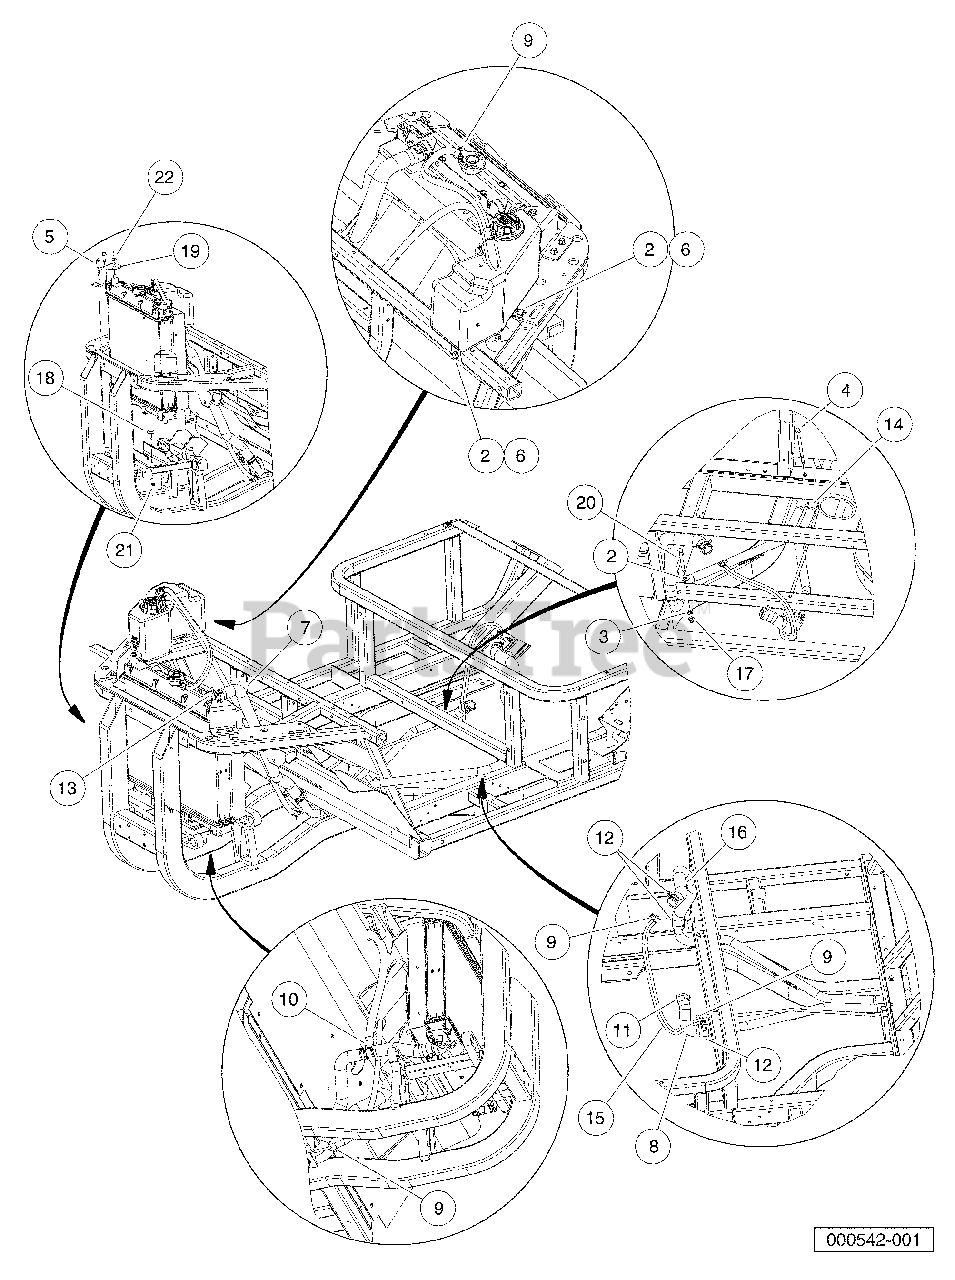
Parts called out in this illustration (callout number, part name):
1	Instl, Cooling Sys, Diesel
2	Washer, 5/16 Type B Flat
3	Spacer, 0.720"
4	Bolt-hex Fl, M8 X 1.25 X 135
5	Screw, M8X1.25X30, Hex
6	M8-1.25x20 Taptite
7	Hose, Coolant Upper Rad
8	Hose, Coolant Lower Eng
9	Clamp, Hose, CTB 15mm
10	Clamp, Hose, CTB 22mm
11	Clamp, Hose, Ctb 30mm
12	Clamp, Hose, Ctb 35mm
13	Clamp, Hose, Ctb 38mm
14	Clamp, Bar
15	Hose, Vent Tube To Eng, Coolnt
16	Hose, Coolant, Return, Engine
17	Lock Nut, Flg M8 X 1.25 Nylon
18	Bumper, 19mm Stud
19	Bracket, Radiator Support
20	Bolt, M8 X 1.25 X 110
21	Nut Flg, M6 X 1 Serrated
22	Nut Flg, M8 X 1.25 Serrated
